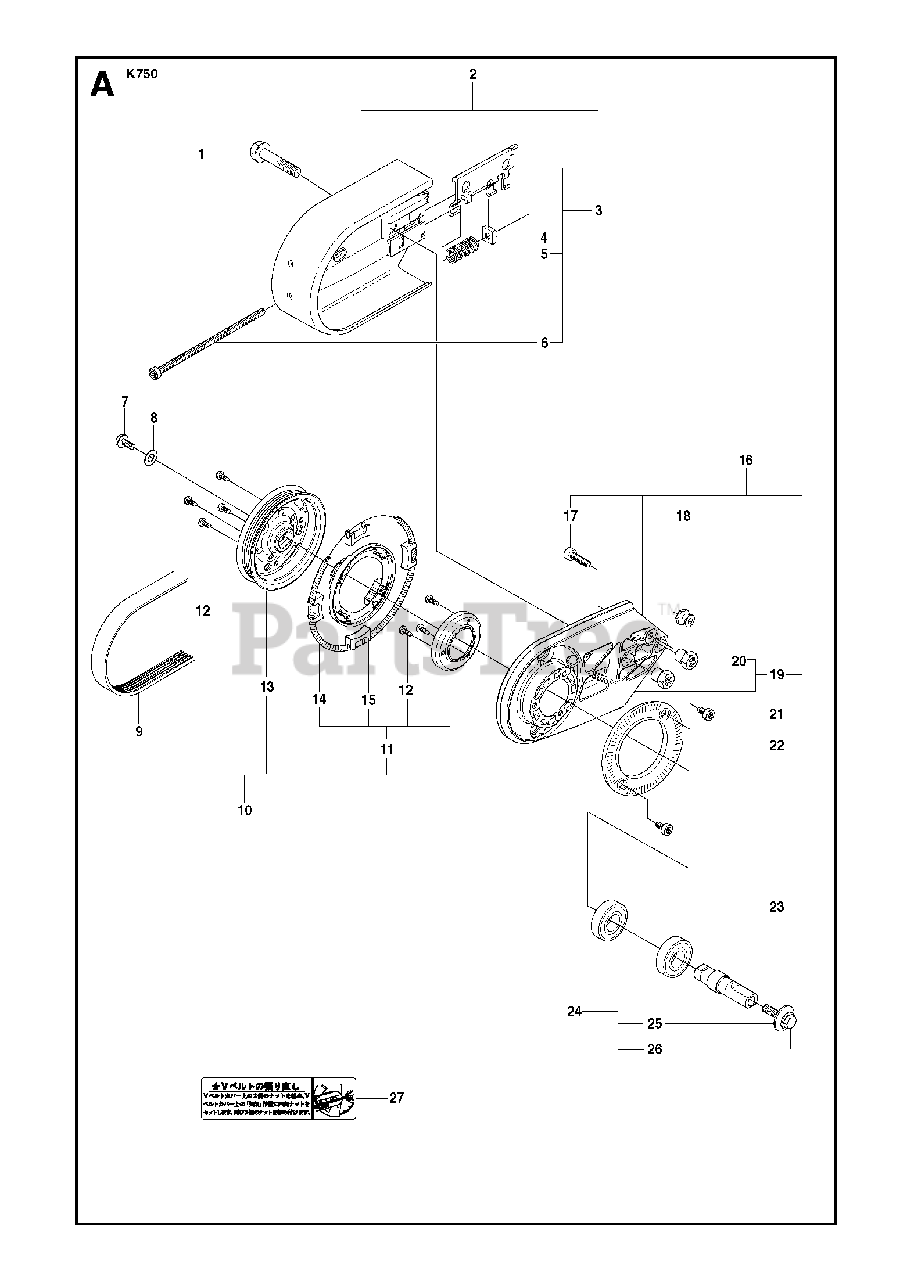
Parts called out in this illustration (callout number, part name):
2	BELT GUARDIncl. 3
3	BELT TENSIONER ASSYIncl. 4 - 6
5	COMPRESSION SPRING
6	SCREW CITXSCM
10	PULLEYIncl. 11 - 13
11	CASSETTEIncl. 12, 14 - 15
12	SCREW CCRPANT
13	PULLEY
16	BEARING HOUSINGIncl. 17 - 19, 21 - 23
17	SCREW ITXSCM
18	TORSION STOP
19	BEARING HOUSINGIncl. 20
21	SCREW ITXSCM
23	BALL BEARING
24	SHAFTIncl. 25 - 26
27	LABELJapan only
